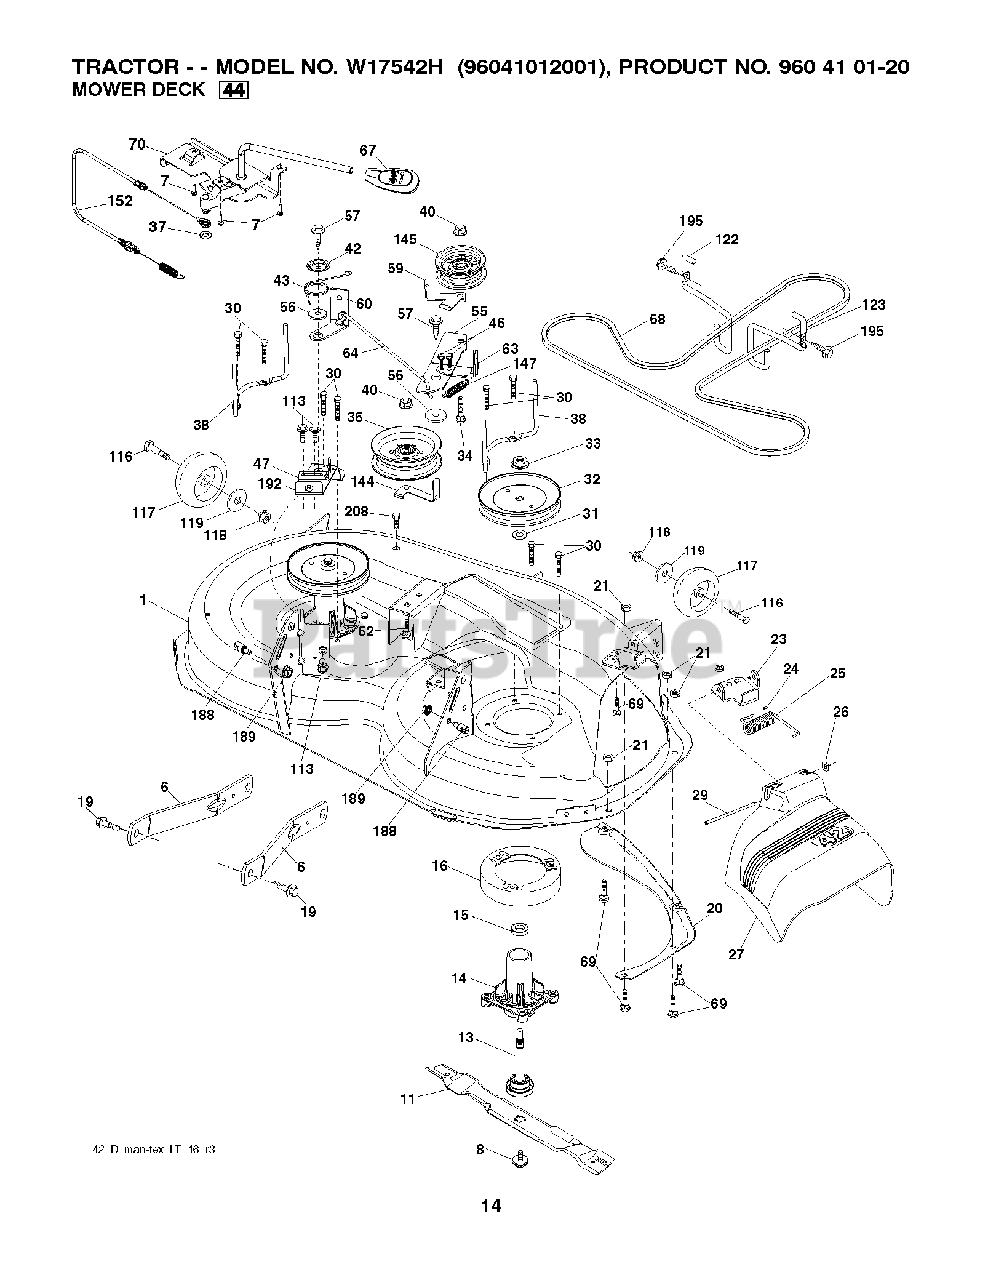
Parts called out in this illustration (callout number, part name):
6	ARM.SUSPENSION.MOWER.R
7	SCREW.#10 X 0.750.BOS (2 2)
8	BOLT.WASHER.ASM.7/16-2
11	42" HI-LIFT BLADE
13	SHAFT.ASM.MDRL.N/GREASE.38
14	HOUSING.MANDREL.4PT.
16	STRIPPER.MANDREL.ROUND.BLACK
19	BOLT.SHOULDER
20	BAFFLE.VORTEX
21	LOCKNUT
23	BRKT.DEFLECTOR.38"2005+
24	CAP-SLEEVE LT
25	SPRING.TORSION.DEFLECT
26	NUT PUSH M
27	SHIELD.DEFLECTOR.MOWER.42"BLAC
29	ROD.HINGE
30	SCREW, WASHER HEAD
31	WASHER.SPACER.MANDREL
32	PULLEY.MANDREL.5.438.PD
33	NUT.FLANGE.LOCK.TOP
34	BOLT.3/8-16X1.50
36	PULLEY.IDLER.2006
38	KEEPER.BELT.LH.MANDREL
40	NUT LOCK FLG 3/8-16 UNC
42	SRPING.TORSION.RETAINE
43	SPRING.TORSION.BRAKE
46	SCREW.1/4-20X5/8
47	BRKT.BRAKE.STAND.LH.
55	IDLER.ARM
56	SPACER.RETAINER
57	SCREW 3/8-16X1
59	GUARD, BELT
60	ARM BRAKE MOWER
62	BOLT
64	LINK BRAKE
68	BELT.DRIVE.MOWER.TEX.42"
69	BOLT
70	CLUTCH.ASM.MANUAL.LT.TEX
113	BOLT.5/16HEX.WHS.HD
116	BOLT M
117	WHEEL.GAGE.HALF.SPOKED
118	LOCKNUT
119	WASHER
122	KEEPER BELT ENGINE LH
123	KEEPER BELT RH
144	KEEPER.BELT.MOWER
145	PULLEY.IDLER.48"PRIMARY
147	RETURN SPRING
152	CLUTCH CABLE
188	STUD.FASTNER.W/ANTI-ROTATE
189	NUT LOCK HEX FLANGE 5/16-18
192	BRKT.CLUTCH.CABLE
195	SCREW, 3/8-16X3/4
208	SCREW 3/8-16X1/2
